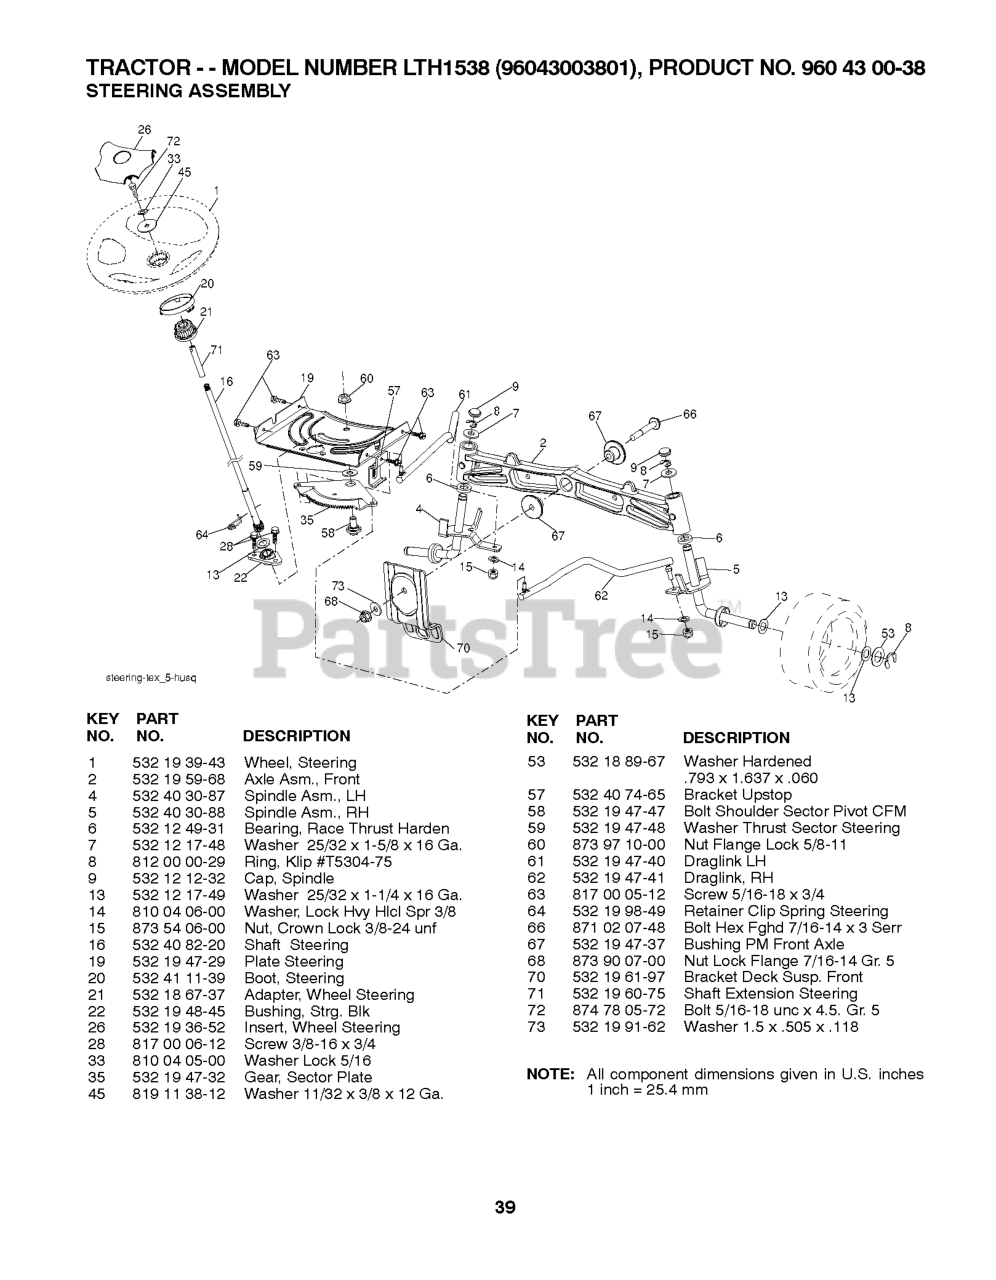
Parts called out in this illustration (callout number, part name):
1	WHEEL.STEERING.LEGEND2.GRY
2	AXLE.CAST.IRON
4	SPINDLE.WELDED.LH.15"TEX
5	SPINDLE.WELDED.RH.15"T
6	THRUST WASHER
9	CAP.SPINDLE.BLACK
14	WASHER, LOCK 3/8
15	NUT CROWNLOCK 3/8-24
16	SHAFT.STEER.SPLINED.TEX.3 HIGH
19	PLATE.STEER.DDL.NLT/NG
20	BOOT, STEERING
21	ADAPTER, WHEEL STNG..
22	BUSHING.ASM.STEERING.A
26	INSERT.CAP.STRG.WH.GRAY
28	SCREW, 3/8-16X3/4
33	WASHER.LOCK.HVY.HLCL.SPR.5/16
35	GEAR.SECTOR.PLATE.DDL.
45	WASHER.11/32
53	WASHER.HARDENED
57	BRACKET.UPSTOP.TEX
58	BOLT.SHOULDER.SECTOR.P
59	WASHER.THURST.SECTOR.S
60	NUT FLANGE LOCK 5/8-11
61	DRAGLINK.LH.BALLSTUD.D
62	DRAGLINK.RH.BALLSTUD.D
63	SCREW
64	RETAINER.CLIP.SPRING.S
66	BOLT HEX FGHD 7/16-14 X 3 SERR
67	BUSHING.PM.FRONT AXLE
68	NUT.LOCK.FLANGE.7/16
70	BRKT.DECK.SUSPENSION.F
71	SHAFT EXTENSION STEERING
72	BOLT YT
73	WASHER.1.5X.505X.118
